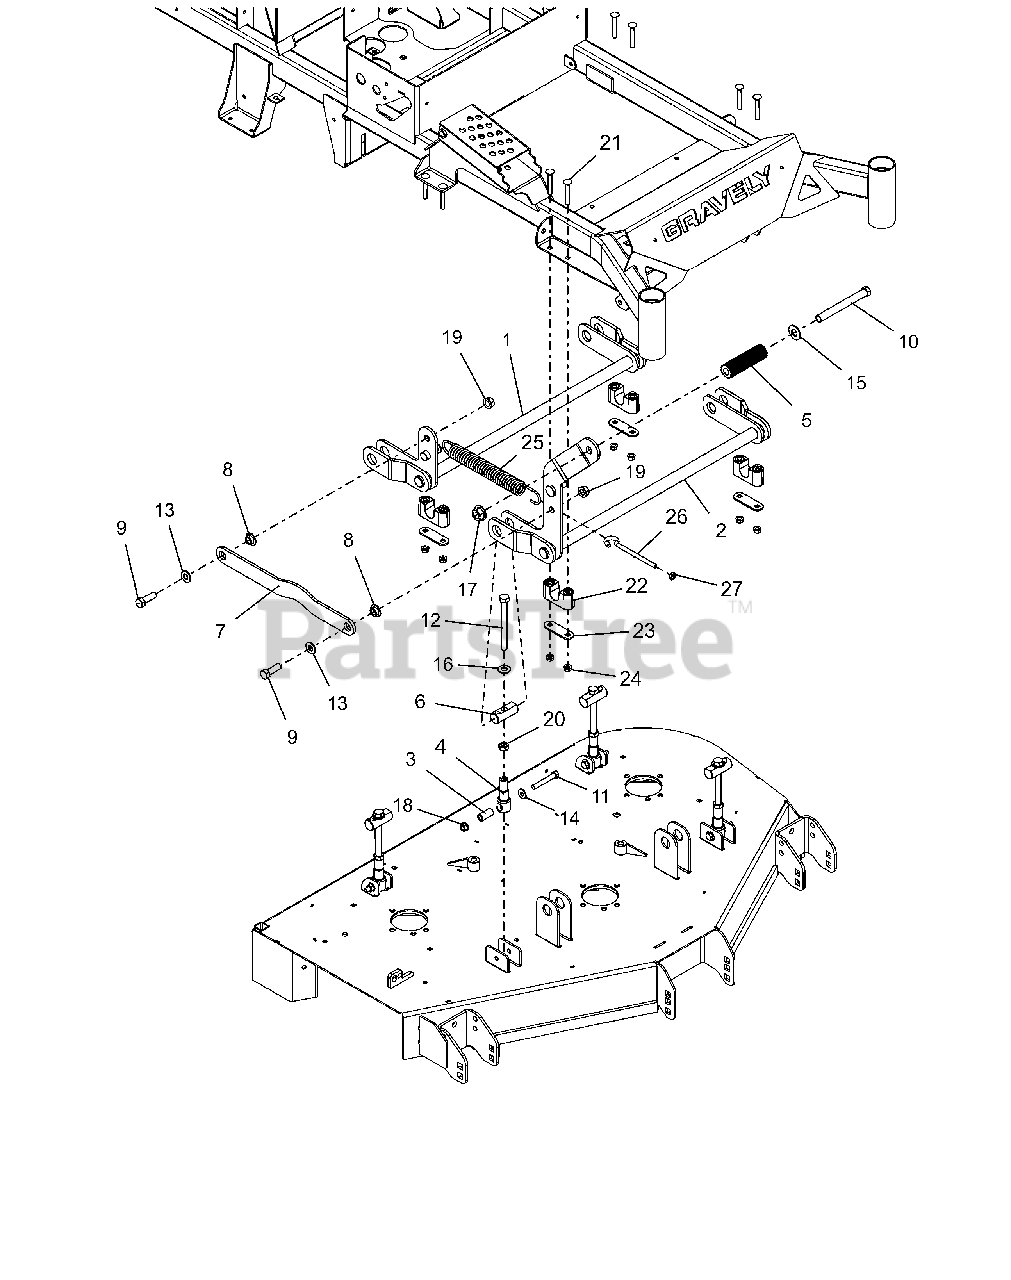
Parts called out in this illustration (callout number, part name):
1	WLDMT, COMPACT REAR DECK LIFT
2	WLDMT, COMPACT FRONT DECK LIFT
3	SPACER, DECK LEVELING
4	LINK, DECK LIFT FORMED
5	ROD, FOOT PEDAL (BLACK)
6	PIN, DECK LIFT
7	LINK, DECK LIFT
8	BSHG, FLG .515X.750X.360X1.12
9	BLT,HEX .50-13X1.50 G5 ZCC
10	BLT, HEX .62-11X5.50 G5 FBP
11	BLT, HEX .38-16X2.50 G5 ZCC
12	BLT, HEX 0.5-13X5S GR5 ZCC
13	WSHR,FLT .531X1.062X.095 ZCC
14	WSHR,FLT .375X.875X.083 ZCC
15	WSHRFLT 5/8SAE CARBHARD FBP
16	WSHR, FLT .557X1.040X.102 ZCC
17	NUT,FLG-TOP LK .625-11 FBP
18	NUT-LK-CTR-FLG .375-16 GF ZCC
19	NUT-LK-CTR-FLG .500-13 GG ZCC
20	NUT-JAM .500-13 G2 ZCC
21	BLT, RHSSN.31-18X2.25 G5 ZCC
22	ASM-BUSHING, DECK LIFT
23	PLATE, BEARING SUPPORT
24	NUT,LK-CTR-FLG .31-18 GF ZCC
25	SG-TENS .162X1.25X8.25 WLD 25
26	BOLT,.38-16 X 4.25-.62 DIA EYE
27	NUT-JAM .375-16 G2 ZCC
